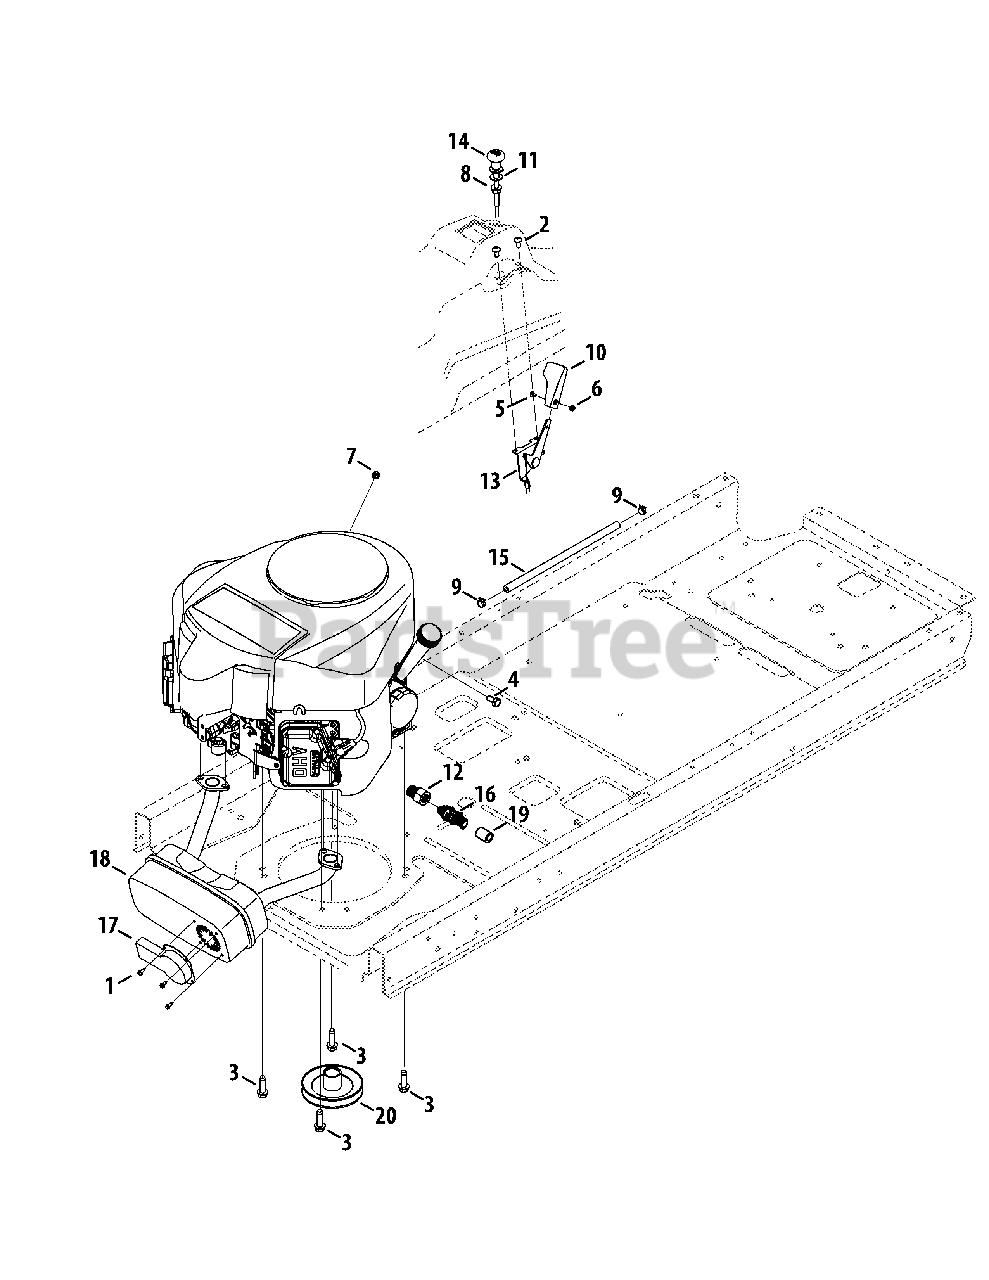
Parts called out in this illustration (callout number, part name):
1	Hex Washer Screw, #8-18 x .500
2	Screw, 1/4-20 x .50
3	Tap Screw, 3/8-16 x 1.25
4	Hex Screw, M8-1.25 x 16
5	Screw, #8-32 x .375
6	Hex Nut, #8-32
7	Flange Lock Nut, 1/4-20
8	Flange Lock Nut, 3/8-16
9	Hose Clamp, .490 Dia.
10	Throttle Control Knob
11	Flat Washer, .406 x .875 x .059
13	Throttle Cable
14	Choke Cable
15	Fuel Hose, 1/4
17	Deflector, Muffler, Long
18	Muffler, Kawasaki Twin
19	Oil Drain Hose
20	Engine Pulley
